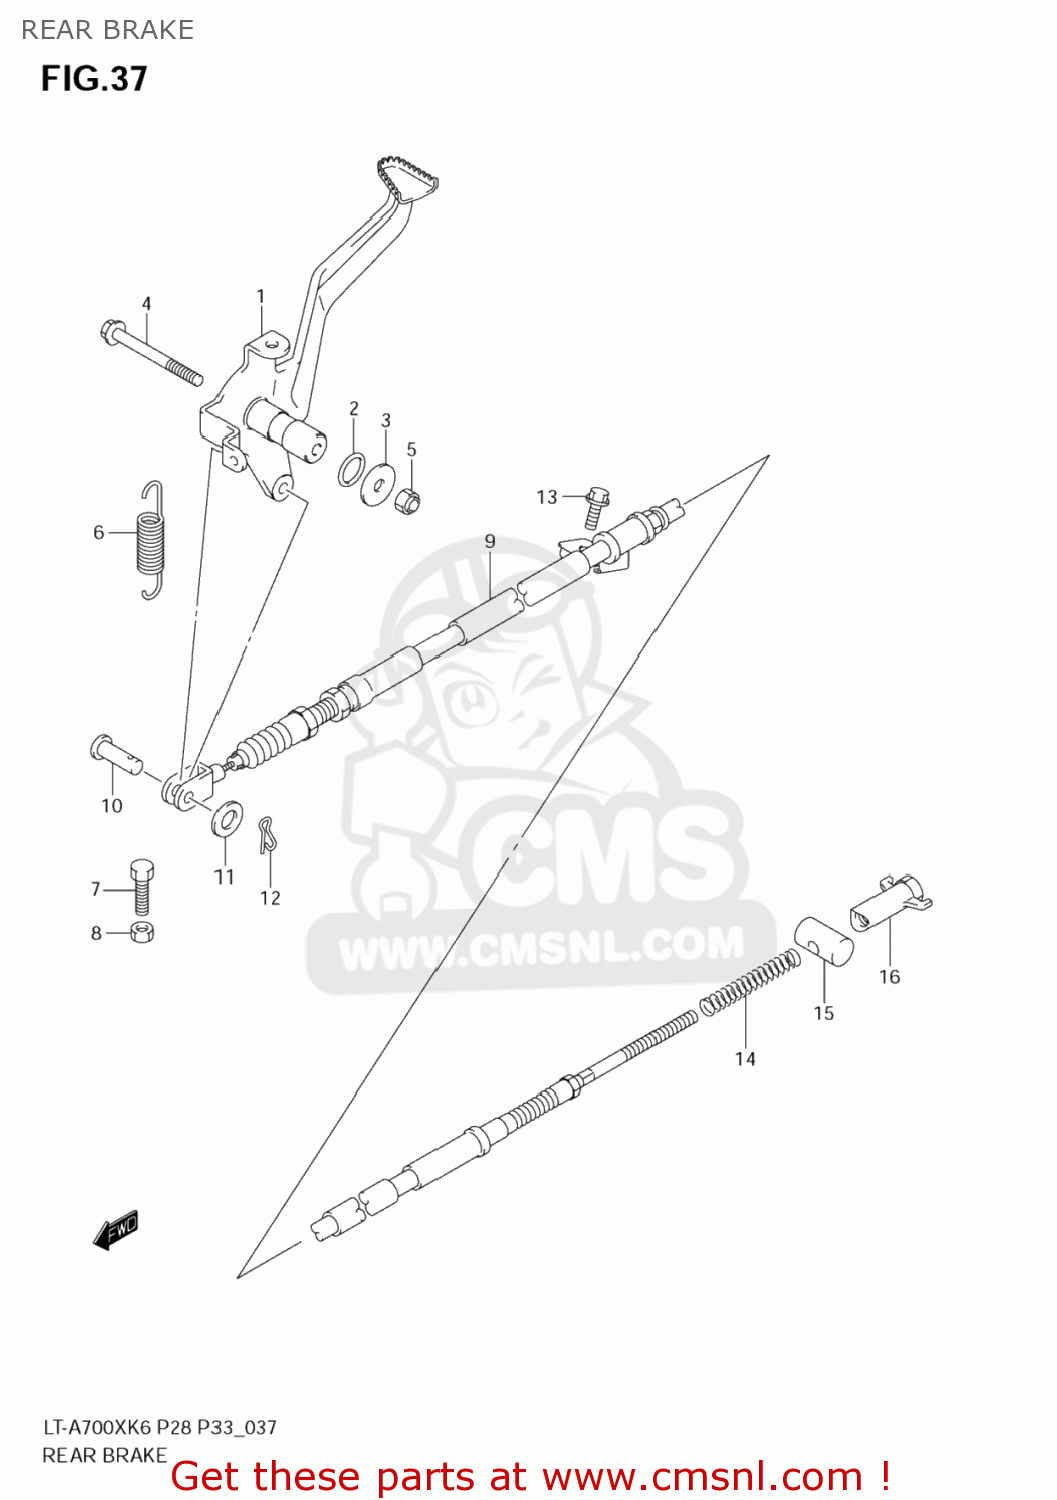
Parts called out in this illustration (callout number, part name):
1	PEDAL,BRAKE
2	O RING(D:2.5,ID:13.8)
3	WASHER(6.5X22X2.3)
4	BOLT
5	NUT
6	SPRING
7	BOLT
8	NUT 6MM
9	CABLE,RR BRAKE
10	PIN(L:17.5)
11	WASHER
12	CLIP
13	BOLT
14	SPRING
15	PIN
16	NUT
